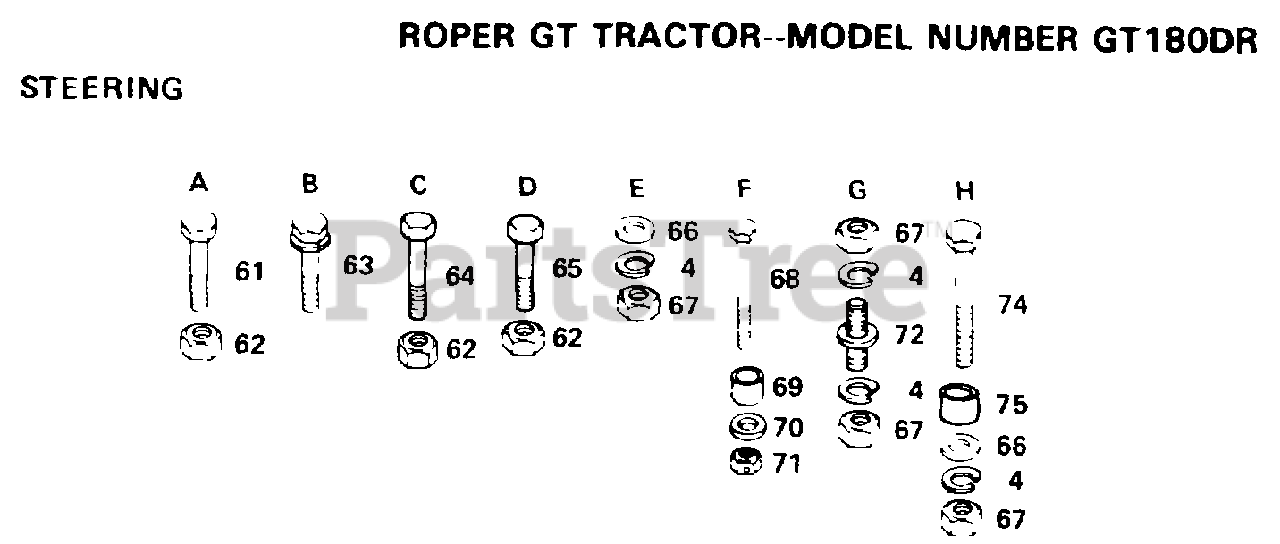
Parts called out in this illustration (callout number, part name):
4	LOCKWASHER
63	SCREW
64	BOLT
65	BOLT
66	WASHER
67	NUT.HEX.3/8-16UNC
69	BUSHING LT
70	WASHER
75	SPLIT SPACER YTV
